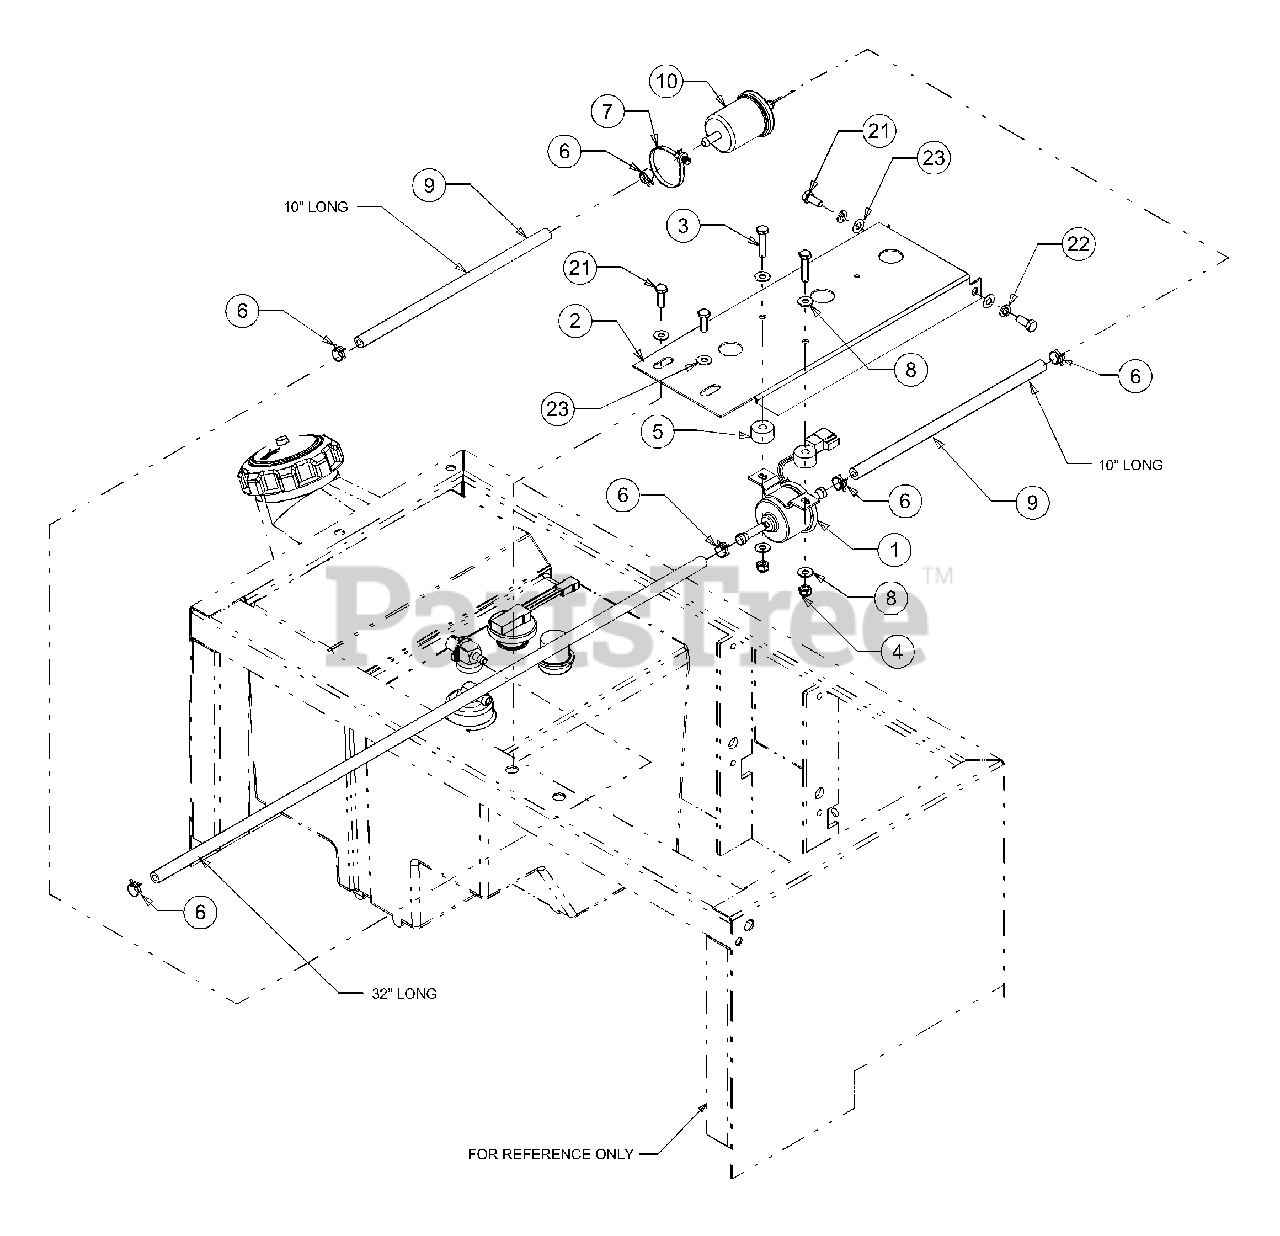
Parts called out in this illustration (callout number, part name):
1	Pump Assembly, Fuel
4	Nut, Nylon Hex Lock, 1/4-20, Gr8
5	Bushing, .96 OD x .50
6	Clamp, Hose
7	Cable Tie, 19 x 8.39
8	Washer, Flat, .271 x .630 x .065
9	Hose, Fuel Line
10	Filter, Fuel
21	Hex Screw, 5/16-18 x .75
22	Washer, Lock, 5/16
23	Washer, Flat, .330 x .687 x .030
